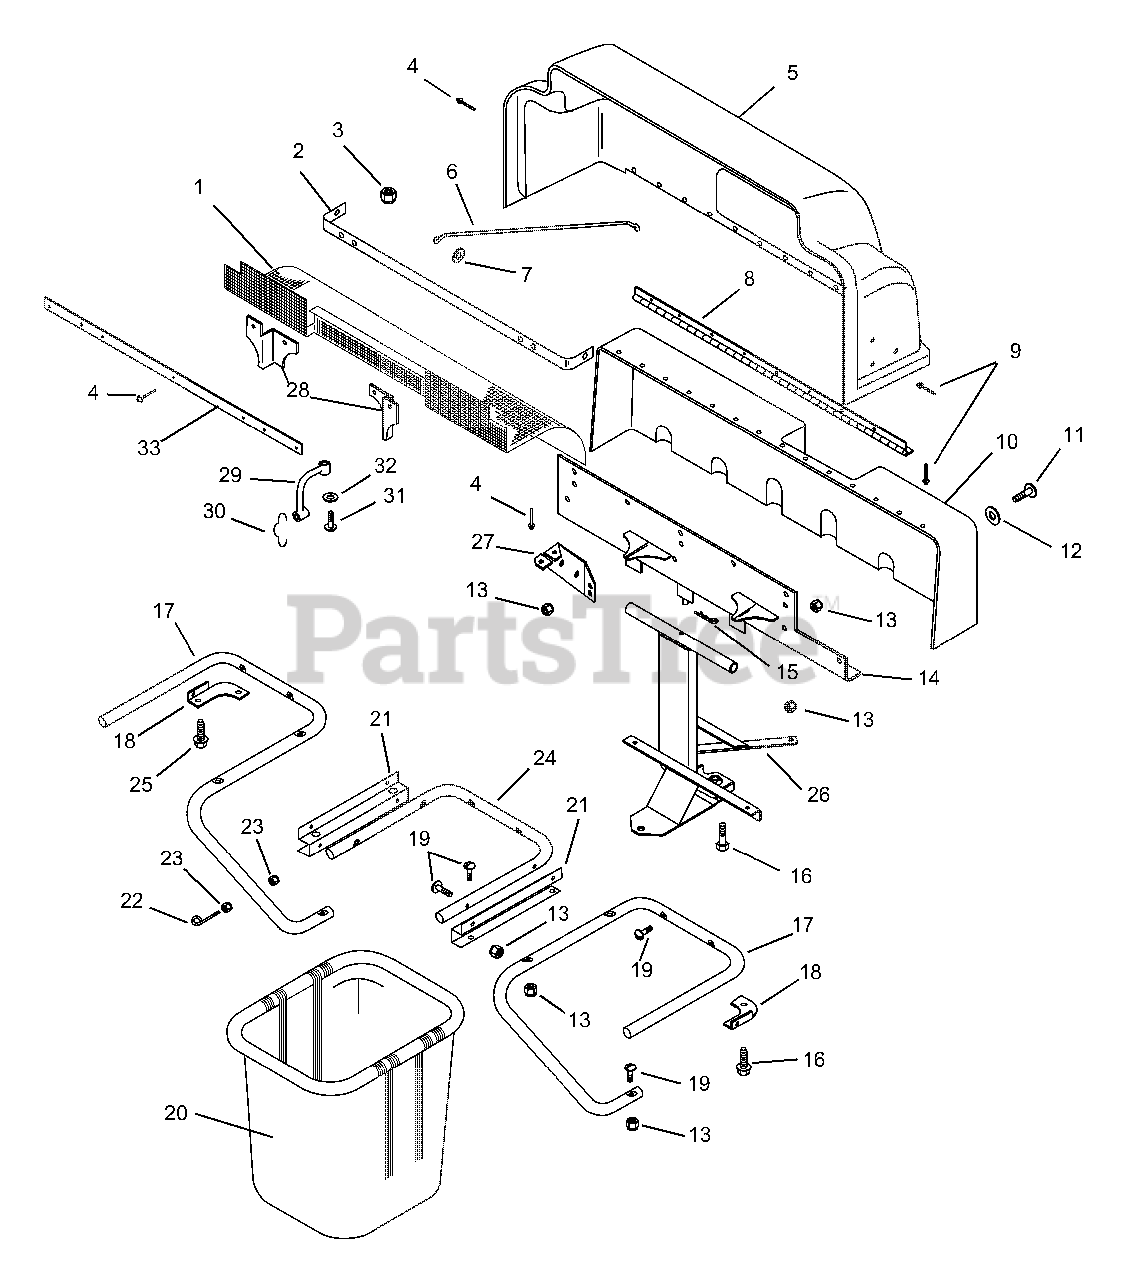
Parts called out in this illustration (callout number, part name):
2	SCREEN MOUNTING BRACKET
3	@NUT-LK-NYL 10-24 W/INSRT YWZC
4	RVT-POP.187X.527 DOME ST
5	HINGED COVER W/DECALS
7	@WSHR-FL-STL .188X.438X.049 YZ
8	HINGE- 2.0"X35.0"
9	RVT-POP .187X.402 DOME ST
10	STATIONARY COVER
11	@BLT-HEX .31-18X.75 GR5 YWZC
12	WSHR-FL-STL .328X.875X.062YWZC
13	@NUT-LK-CTR .31-18 YWZC
14	MOUNTING BRACKET
15	PIN-HAIR INT .08X.38X1.42 YWZC
16	@BLT-HEX .50-13X1.25 GR5 YWZC
17	RIGHT TUBE
17	LEFT TUBE
18	RH CORNER BRACKET
18	LH CORNER BRACKET
19	SCR-MCH .31-18X1.50 CROVCNTRS
20	GRASS BAGGER BASKET
21	TUBE BRACKET
22	EYEBOLT
23	@NUT-LK-CTR .25-20 YWZC
24	CENTER TUBE
25	@SCR-TAP .31-18X.50 HWH TR YWZ
26	BAGGER FRAME
28	BAFFLE LH
28	BAFFLE RH
29	BATTERY STRAP
31	@SCR-MCH 10-24X1.00 HWH YWZC
32	@WSHR-FL-STL.219X.50X.049 YWZC
33	GUARD - SCREEN
